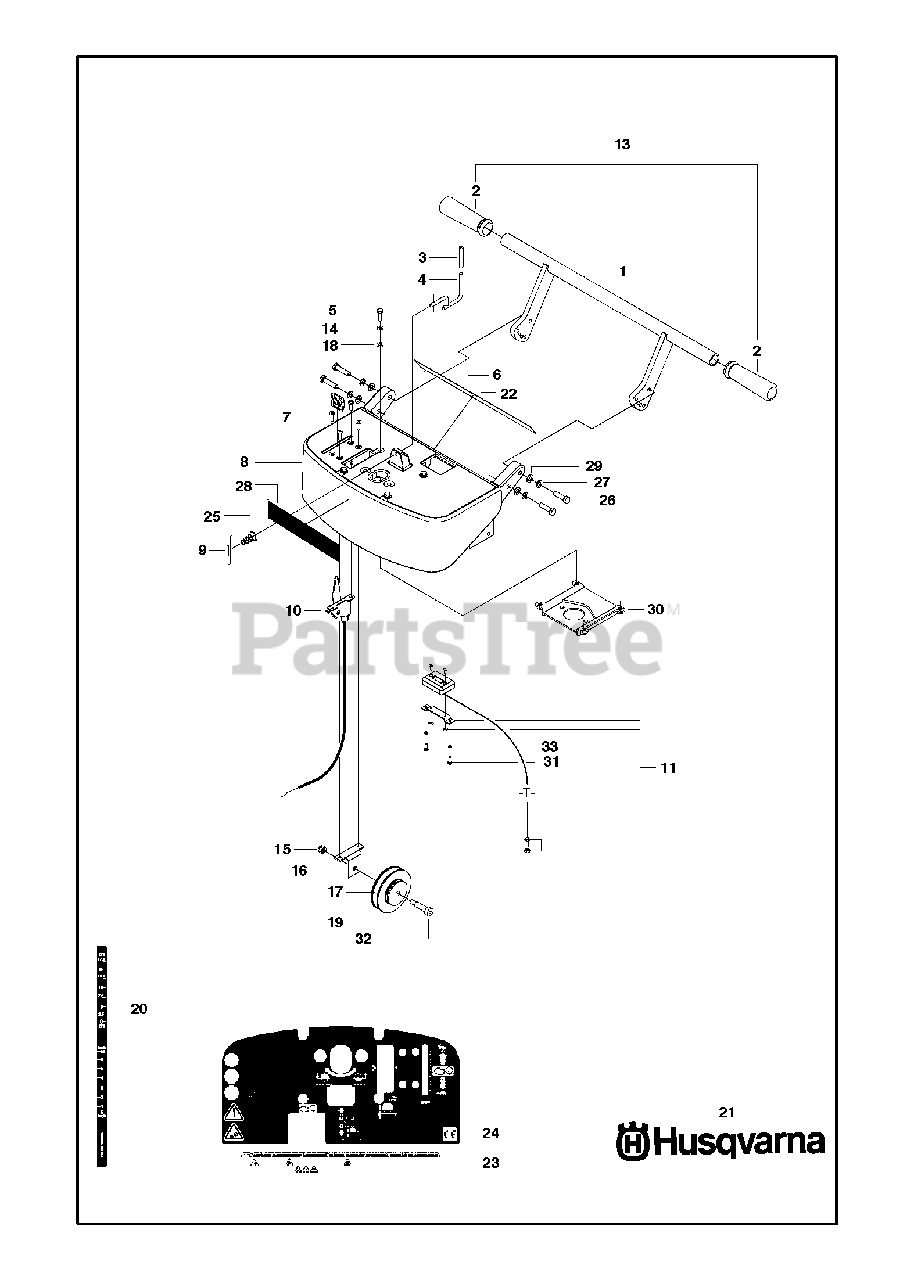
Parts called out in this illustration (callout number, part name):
15	HEXAGON LOCKING NUT
27	SPRING WASHER
29	WASHER
33	SPRING WASHER 4.1X7.1
